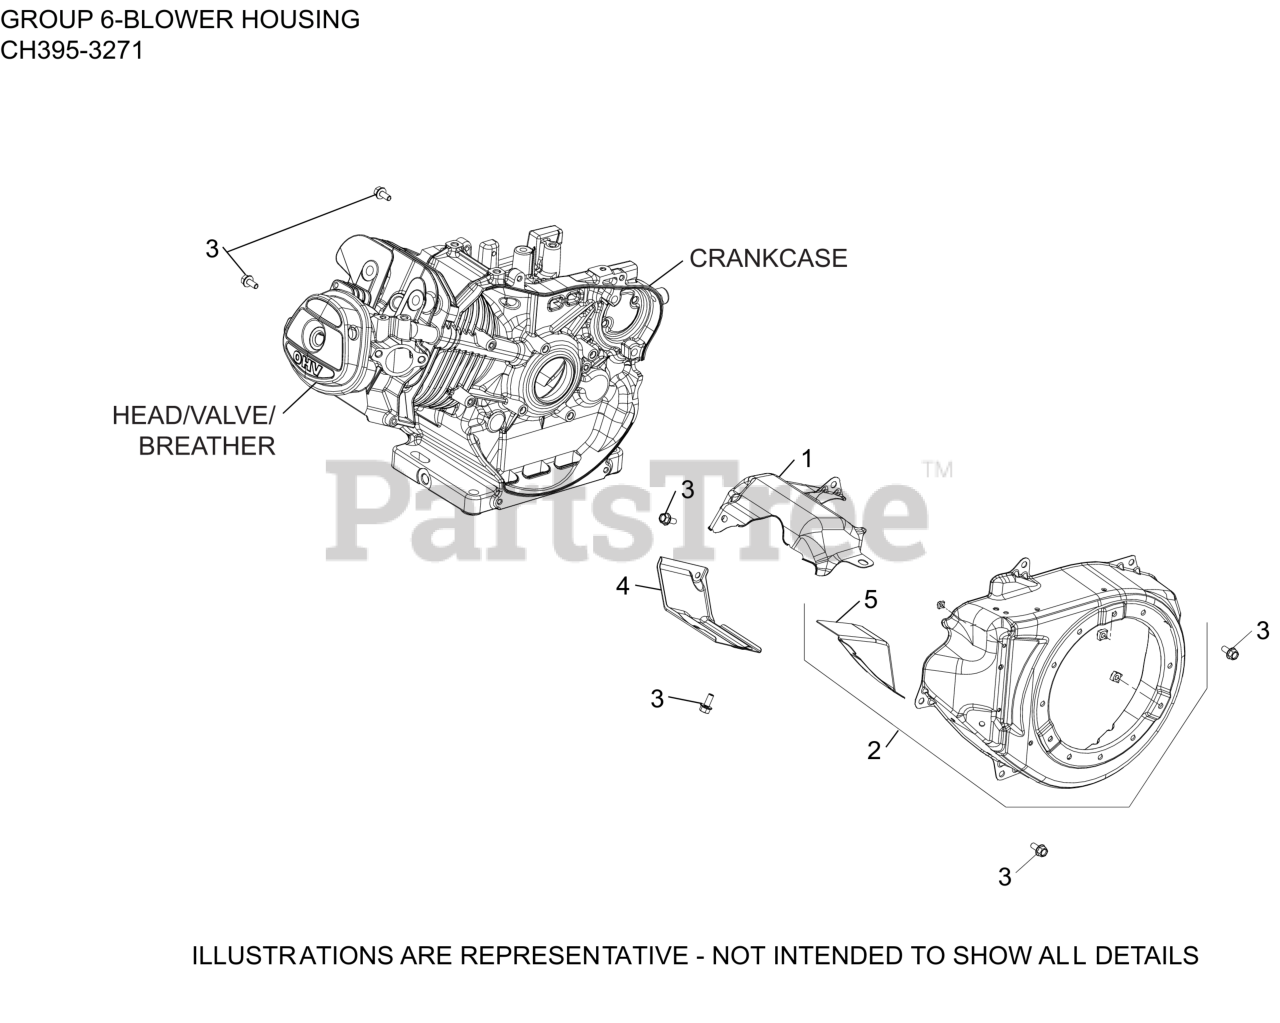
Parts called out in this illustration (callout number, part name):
1	SHIELD, UPPER HEAT
2	KIT, BLOWER HOUSING
3	SCREW, HEX FLANGE (M6)-USE 25 086 433-S
4	SHIELD, CYLINDER HEAD
5	SHIELD, OUTSIDE CYLINDER HEAD
